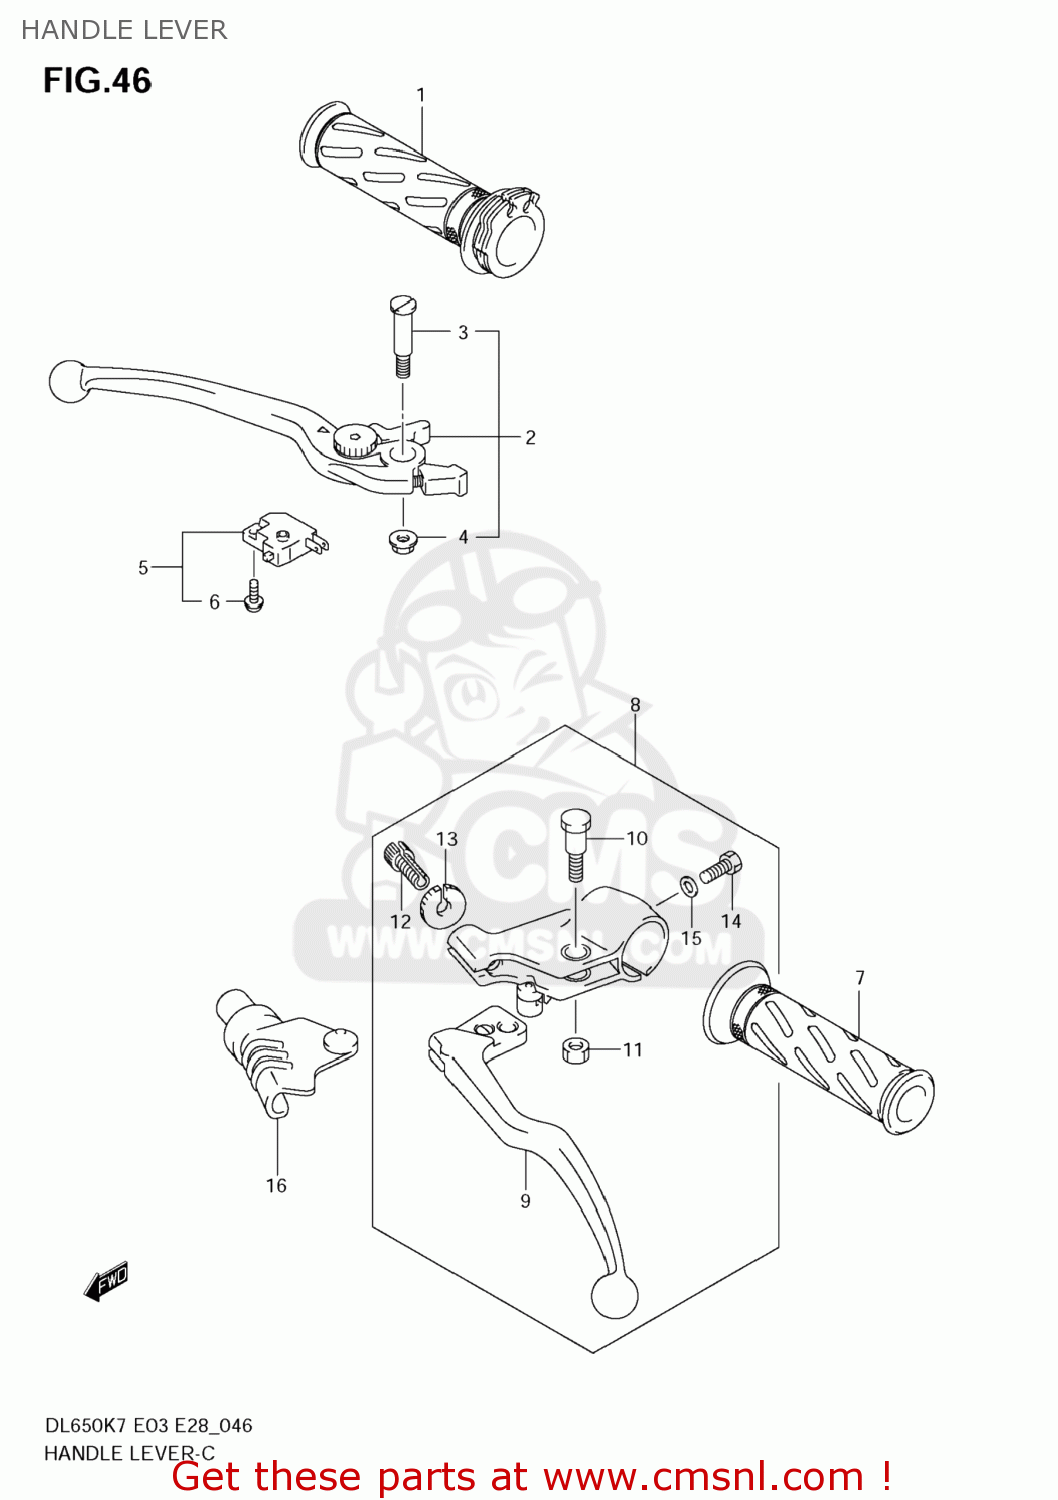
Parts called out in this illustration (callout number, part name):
1	GRIP,THROTTLE
2	LEVER ASSY,BRA
3	BOLT,LEVER
4	NUT
5	SWITCH ASSY,ST
6	SCREW
7	GRIP,LEFT
8	LEVER ASSY,CLUTCH
9	LEVER,CLUTCH
10	BOLT,LEVER SET
11	NUT
12	ADJUSTER,CABLE
13	NUT,CABLE ADJUSTER
14	BOLT
15	WASHER
16	COVER,CLUTCH LEVER
